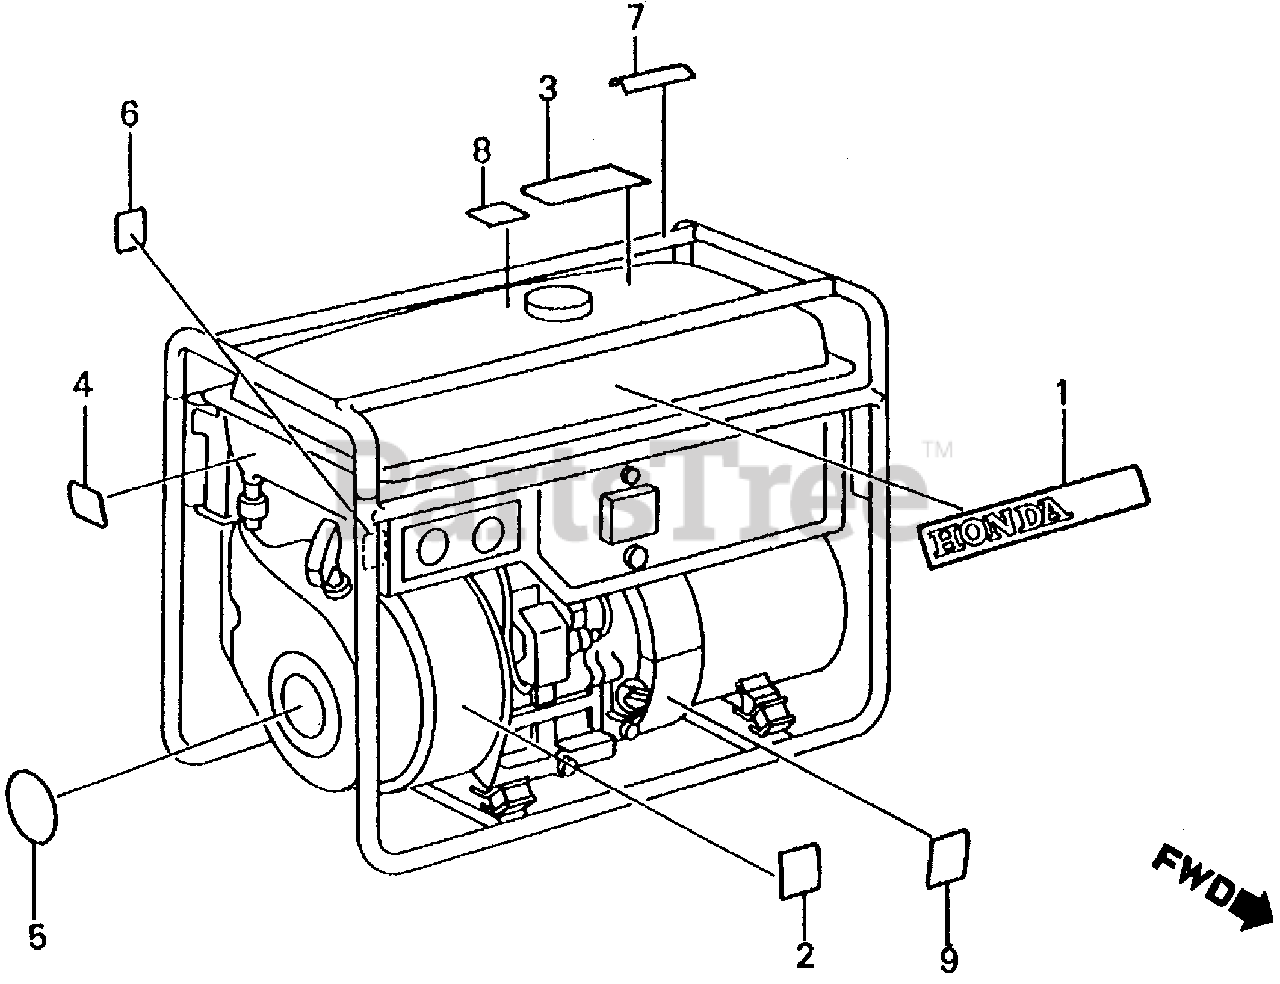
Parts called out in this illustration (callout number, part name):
2	PLATE, CAUTION
3	MARK, CAUTION (ENGLISH/FRENCH)(SPANISH)
4	MARK, CHOKE
5	LABEL, C.D.I. OIL ALERT
6	MARK, AIR CLEANER (ENGLISH)
7	MARK, EX. CAUTION (ENGLISH/FRENCH)
8	MARK, CAUTION (CO)(ENGLISH/FRENCH)(SPANISH)
9	MARK, OIL CAUTION
